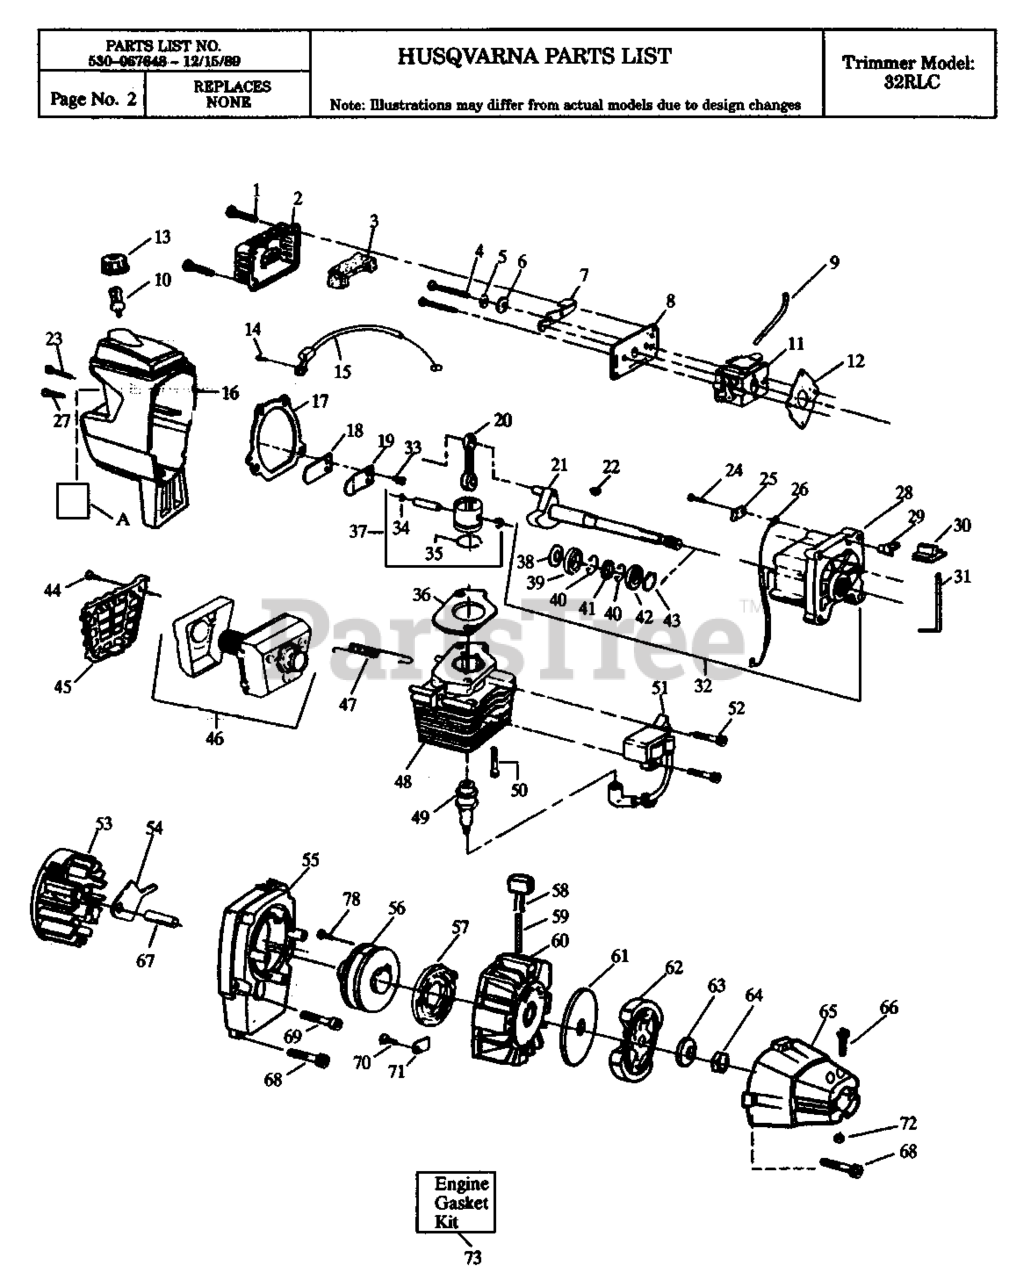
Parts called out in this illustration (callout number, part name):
1	SCREW-10-24 X 13/16
2	COVER-FILTER
3	AIR FILTER
5	SPACER-CHOKE
7	SHUTTER-CHOKE
8	PLATE-AIR FILTER MTG.
9	HOSE. FUEL
10	ASSY-FUEL PICK-UP
11	CARBURETOR (WA-199)
12	GASKET-CARBURETOR
14	SCREW 8-16 X 9/16 (PLAS
15	ASSY-THROTTLE CABLE (SR
16	Shroud & Tank Ass'y.
17	GASKET-C'CASE/SHROUD
18	VALVE-REED
20	ASS'Y-CONNECTING ROD
21	ASSY-CRANKSHAFT
22	KEY-FLYWHEEL
23	SCREW-10-24 X 1" (TAP.)
24	SCREW 6-19X5/8 PLAS.PAN
25	INSULATOR-KILL SWITCH
26	LEAD WIRE-KILL SWITCH
27	SCREW 1/4-20 X 7/8 (TAP
28	Crankcase Ass'y.
29	KILL SWITCH RAMP
30	BUTTON-KILL SWITCH
31	SPRING-KILL SWITCH
32	Crankcase & Crankshaft Ass'y (#21, 28, 38 & 43)
33	SCREW-6-19X5/16PLAST PA
34	WRIST PIN RET.
35	RING-PISTON (HOOKED)
36	GASKET-CYLINDER
37	KIT-PISTON (32CC)
38	SPACER-BEARING
39	Bearing-R8 (inner)
40	RING-RETAINING
41	SEAL-CRANKSHAFT
42	BEARING-R8 (OUTER)
43	RING-RETAINING (SHAFT)
44	SCREW-10-16X9/16SLTD.PH
45	GUARD-MUFFLER
46	KIT-MUFFLER ASS'Y
47	SPRING
48	CYLINDER
49	SPARK PLUG (RCJ-8)
50	SCREW-1/4-20 X 13/16
51	MODULE-IGNITION
52	SCREW-COIL MTG
53	ASSY-FLYWHEEL
54	COUNTERWEIGHT FLYWL 26RLC
55	HOUSING-FAN (ORANGE)
56	KIT-STARTER PULLEY
57	SPRING-STARTER
58	HANDLE-STARTER
60	ASSY-PULLEY HSG (ORANGE
61	WASHER-CLUTCH
62	KIT-CLUTCH ASS'Y
63	WASHER-BELLEVILLE
65	ASSY-CLUTCH HSG (ORANGE
66	SCREW-10-24 X 1-3/8 (UN
67	SPACER-CLUTCH
69	SCREW-10-24X1-3/8-TAPTI
70	SCREW-10-16 X 1/2 HI-LO
72	LOCKNUT-HEX 10-24
73	KIT-GASKET
78	SCREW-6-19X9/32 PAN/SEM
A	USE Number not in Price F
